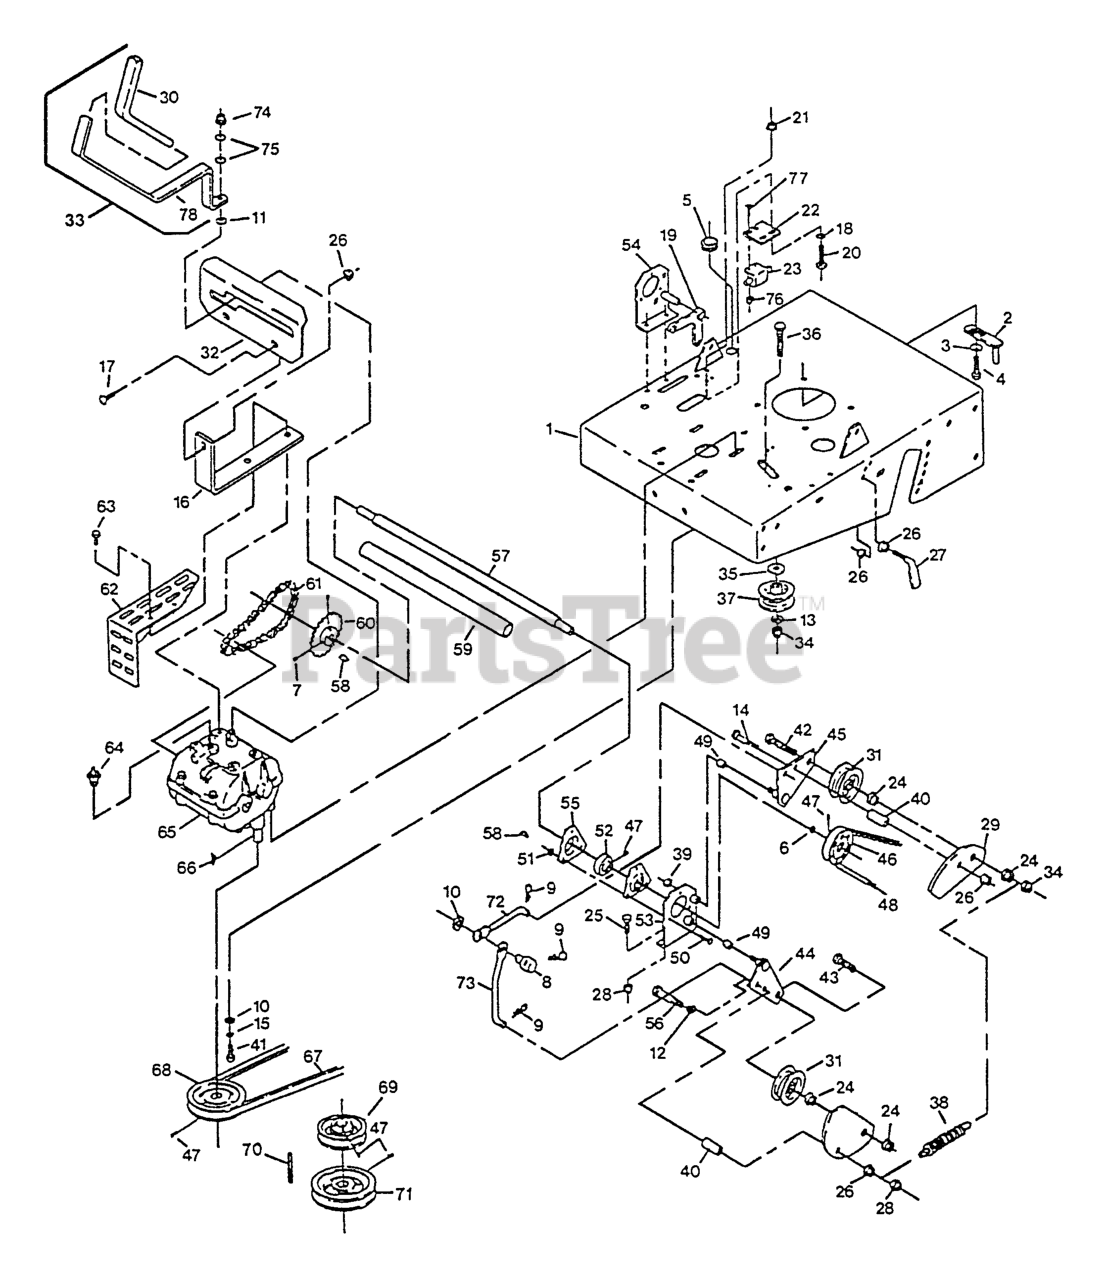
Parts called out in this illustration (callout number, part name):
2	GUIDE - BELT, 32
3	WASHER-SPRING
5	GROMMET
7	SCREW-SET
8	SWIVEL,SHORT ADJUSTING
9	PIN-COTTER
15	WASHER-LOCK
16	BRACKET-PLATE, SHIFT
19	BELLCRANK
22	BRACKET,SAFETY SWITCH
23	SWITCH-OPEN, NORMALLY
31	PULLEY,IDLER
37	IDLER,PULLEY
38	SPRING-IDLER
39	NUTTORQUE ZKPLT
44	ARM - IDLER
45	ARM - IDLER
47	SCREW-SET
48	BELT,COG
57	JACKSHAFT
61	CHAIN,DRIVE
64	SWITCH-START, NEUTRAL
67	BELT,TRANSMISSION
70	KEY,MACH 1/4X1/4X2-5/8
71	SHEAVE,BLADE DRIVE
72	LINKAGE,UPPR CALIPERPLT
73	LINKAGE,LOWER CALIPER RH
